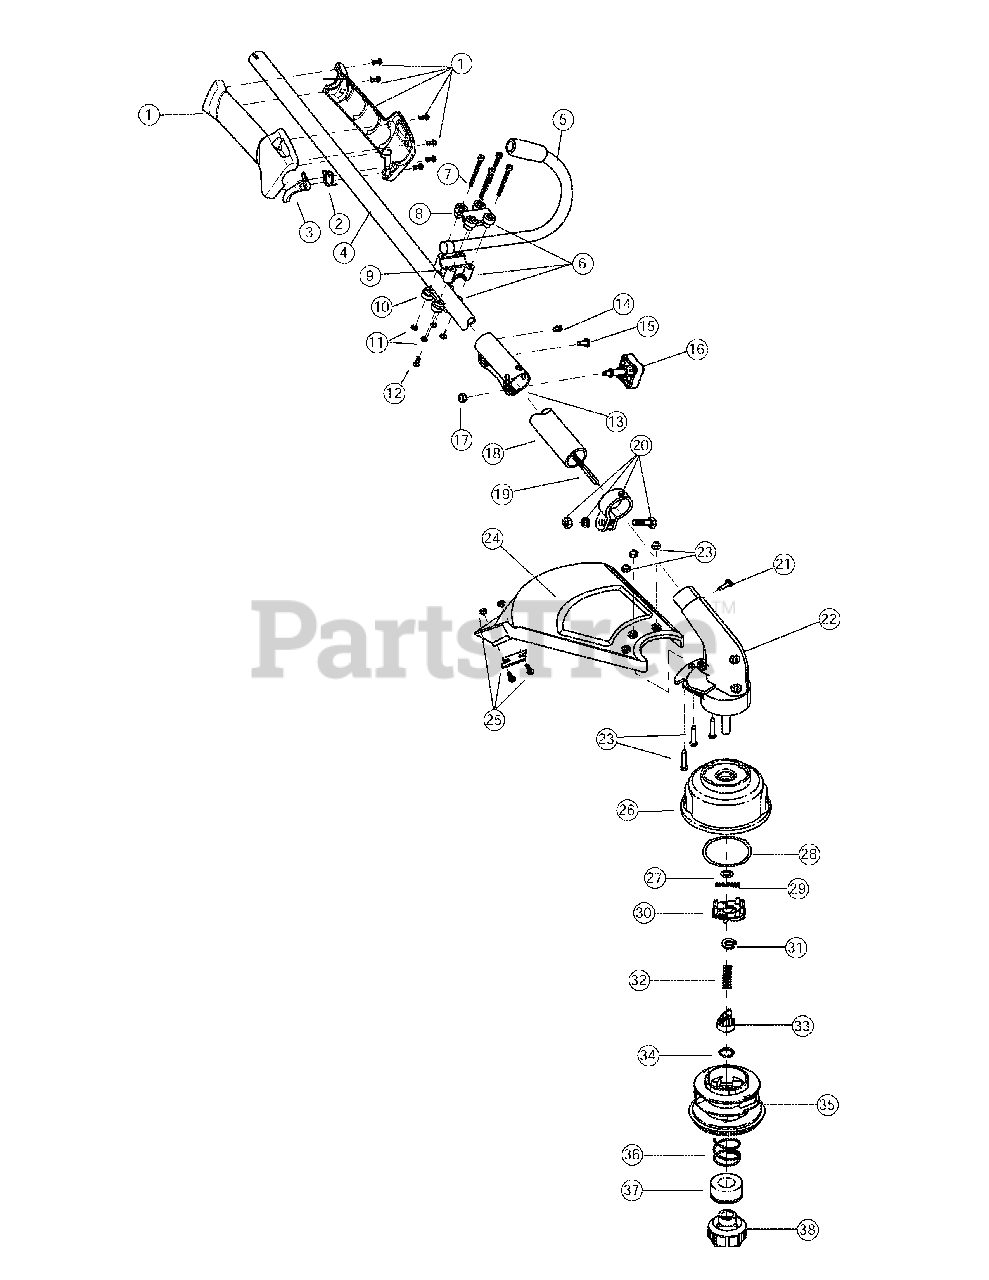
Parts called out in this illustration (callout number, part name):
1	Throttle HousingAssembly (includes 2 & 3)
2	Throttle Trigger Spring
3	Throttle Trigger
4	Upper Drive Shaft Housing Assembly
5	J-Handle Assembly
6	Handle Bracket Assembly (includes 7-12)
8	Upper Handle Clamp
9	Middle Handle Clamp
10	Lower Handle Clamp
12	Anti-Rotation Screw
13	Split Boom Coupler (includes 14-17)
16	Adjustment Knob (Includes 17)
17	Knob Retaining Nut
18	Lower Drive Shaft Housing Assembly
19	Lower Flexible Drive Shaft
20	Lower Clamp Assembly (includes 21)
21	Anti-Rotation Screw
22	Gearbox Assembly (includes 20 & 26-38)
23	Shield Mounting Hardware
24	Shield Assembly (includes 25)
25	Blade Assembly
26	Outer Spool Assembly (includes 27)
27	Retainer
28	Thrust Washer
29	Small Spring
30	Slider
33	Plunger
35	Inner Reel
36	Large Spring
37	Foam Seal
38	Bump Head Knob Assembly (Includes 36 & 37)
